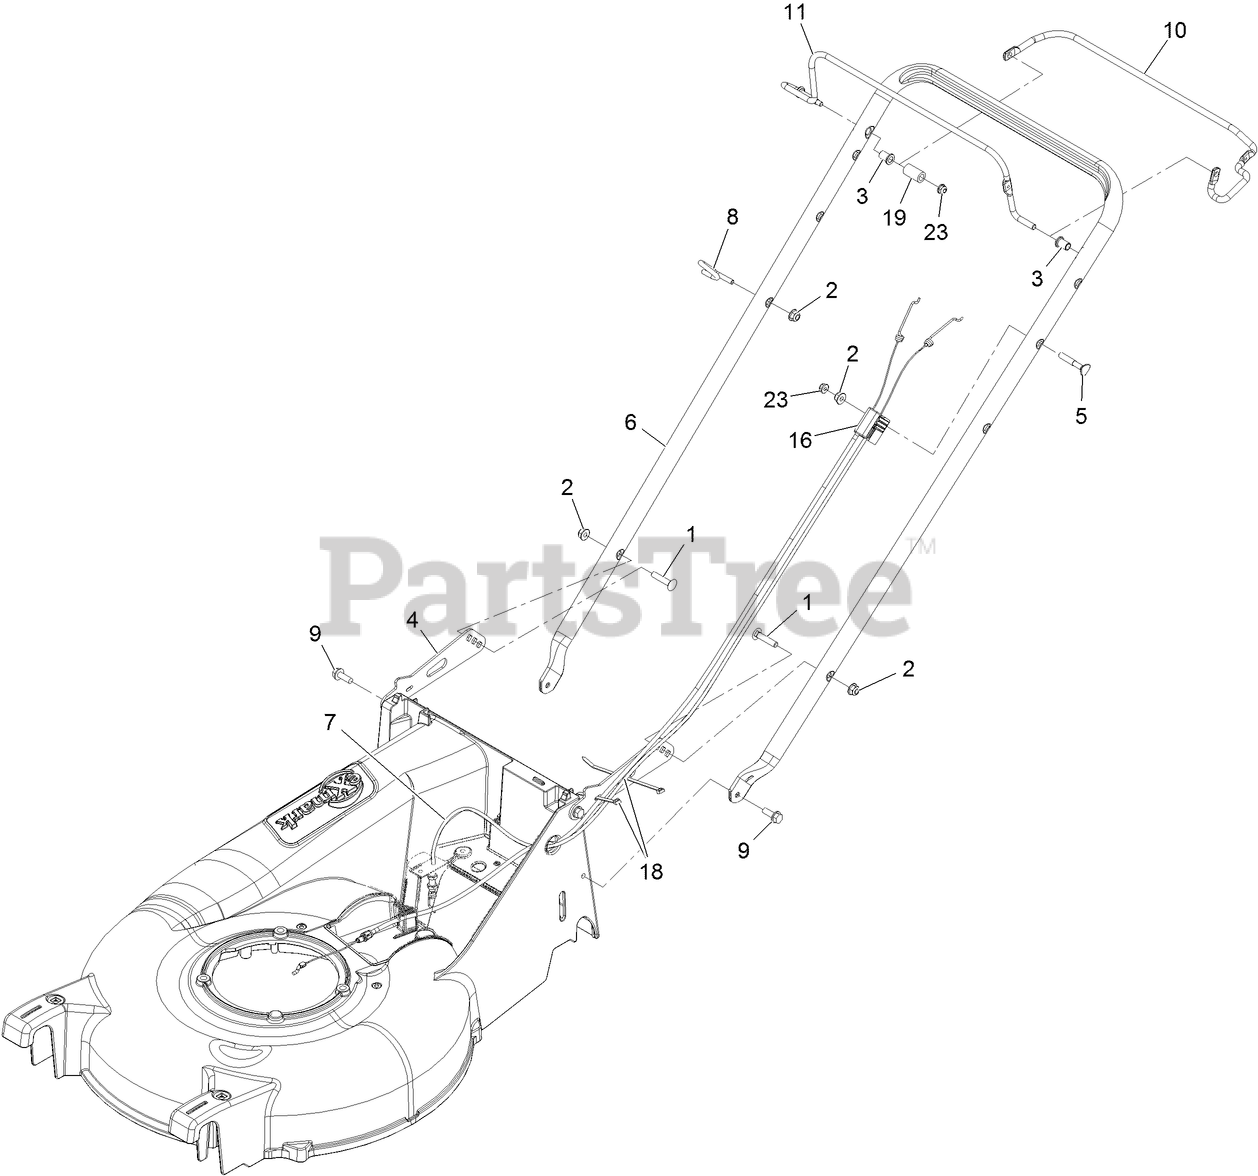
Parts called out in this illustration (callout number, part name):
1	BOLT-CARR
2	NUT-HF, NI
3	BUSHING-HANDLEBAR
4	BRACKET,HANDLEBAR
6	HANDLEBAR-P21
7	CABLE, DRIVE EC21
8	GUIDE,ROPE
9	SCREW-TAPTITE
10	BAIL-DRIVE COATED
16	CABLE-ZONE KAWASAKI
18	TIE-CABLE
